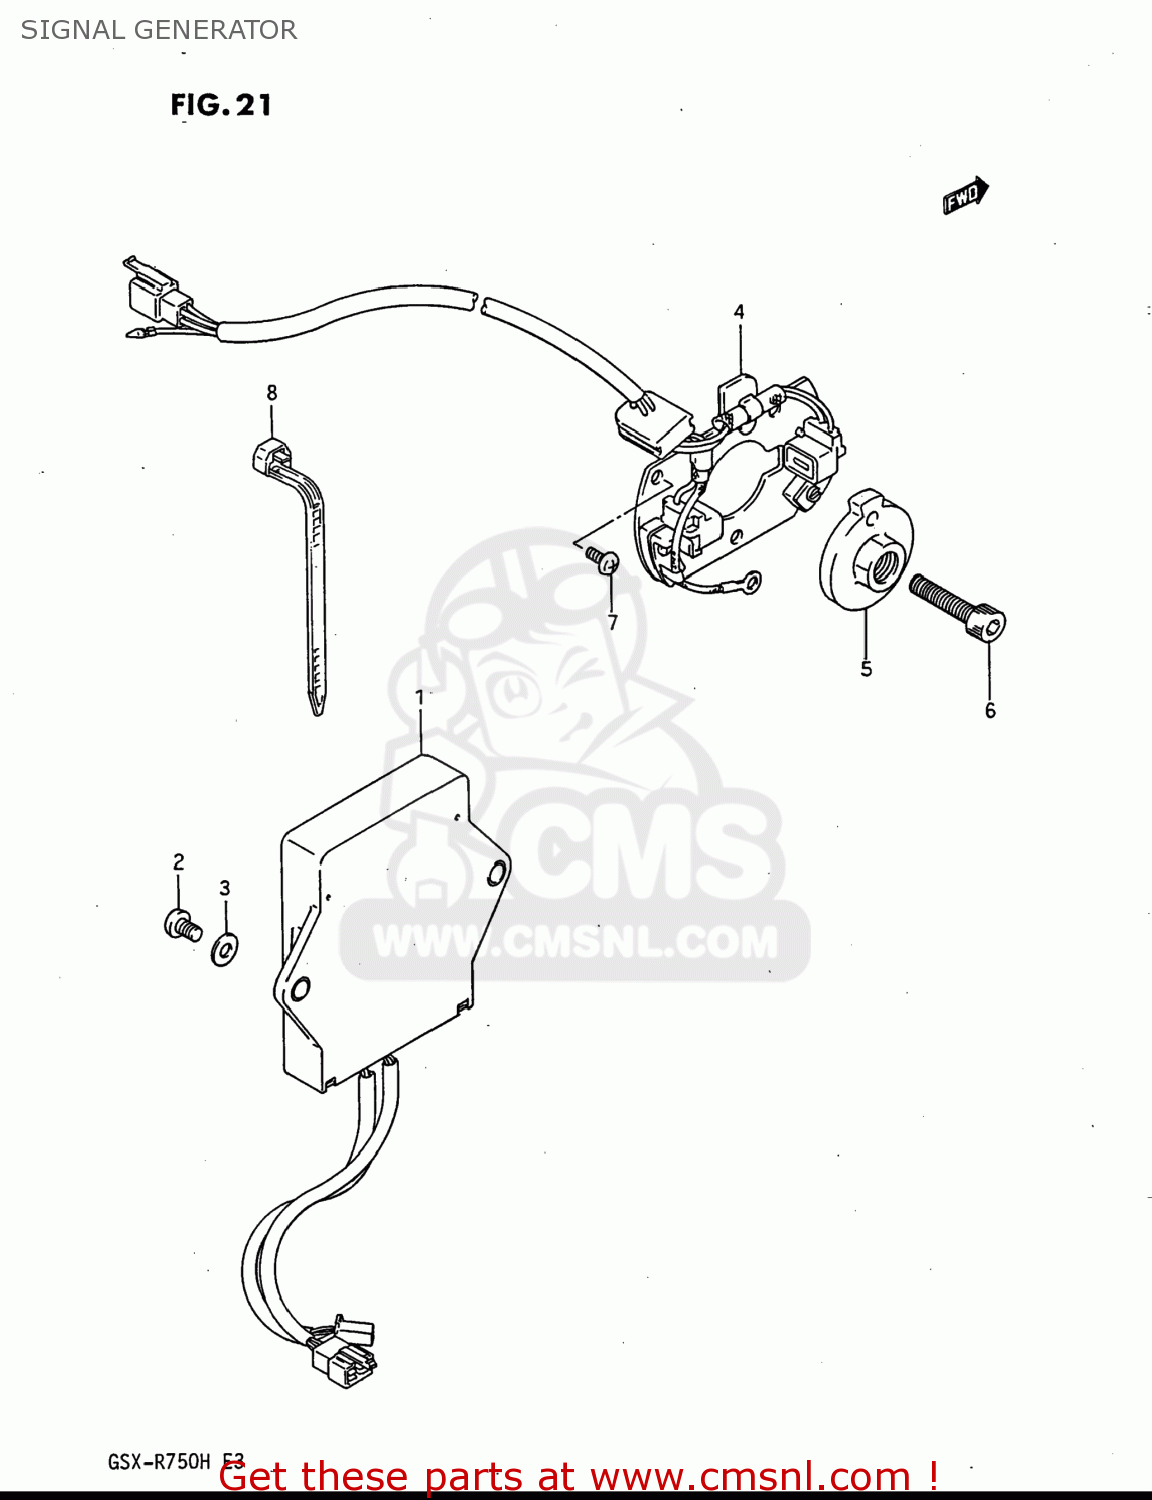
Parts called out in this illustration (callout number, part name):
1	IGNITER UNIT
2	SCREW
3	WASHER, LOWER
4	GENERATOR ASSEMBLY,SIGNAL
5	ROTOR COMP,SIGNAL
6	BOLT
7	SCREW
8	CLAMP(L:95)
